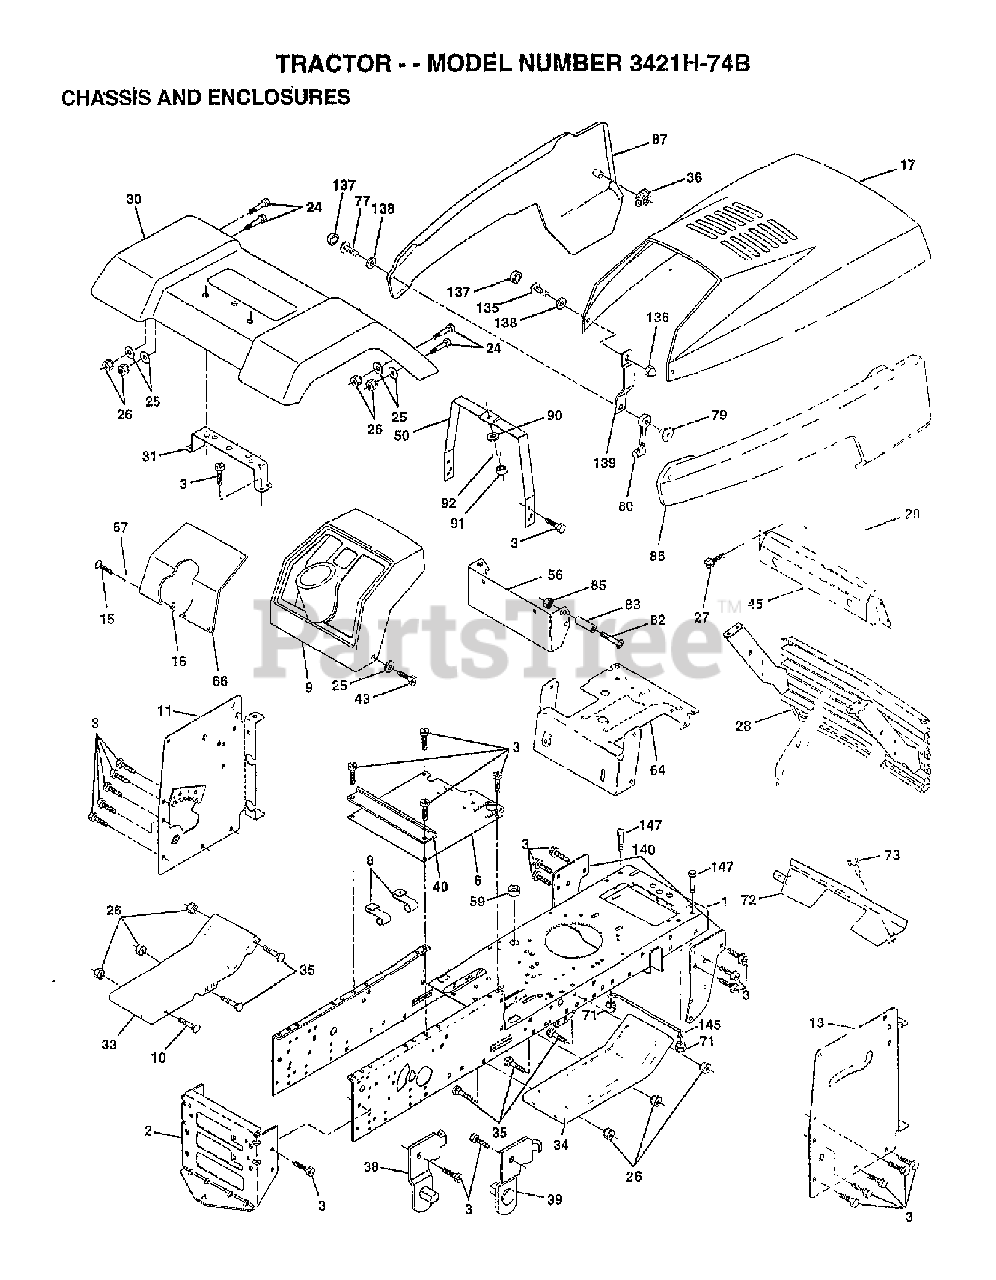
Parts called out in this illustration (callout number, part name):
6	SADDLE FLAT
8	CLIP,INSULATOR
11	PANEL DASH LT
17	Poulan TBD
25	WASHER
26	NUT
30	Poulan TBD
31	BRACKET.SUPPORT.FENDER
33	Poulan TBD
34	Poulan TBD
36	PAL NUT LT
38	BRACKET LH PIVOT
39	BRACKET RH PIVOT
43	SCREW GTV
50	DASH SUPT YP
64	DASH LOWER LT
66	Poulan TBD
67	WASHER
71	NUT.CROWNLOCK.1/4
72	Poulan TBD
73	SCREW CRT
77	SCREW
79	NUT.WELD
80	LATCH.HOOD.
82	SCREW
83	SPACER LT
85	NUT **
86	Poulan TBD
87	Poulan TBD
90	WASHER PM
91	NUT
92	LOCKWASHER
135	SCREW 10-24X3/8
136	NUT
137	SNAP CAP LT
138	WASHER LT
139	BRACKET.SUPPORT.HOOD/PANEL.NLA
140	BRACKET SUSPENSION FRONT
147	BOLT.HEX.1/4.X.3/4.DICHROMATE
